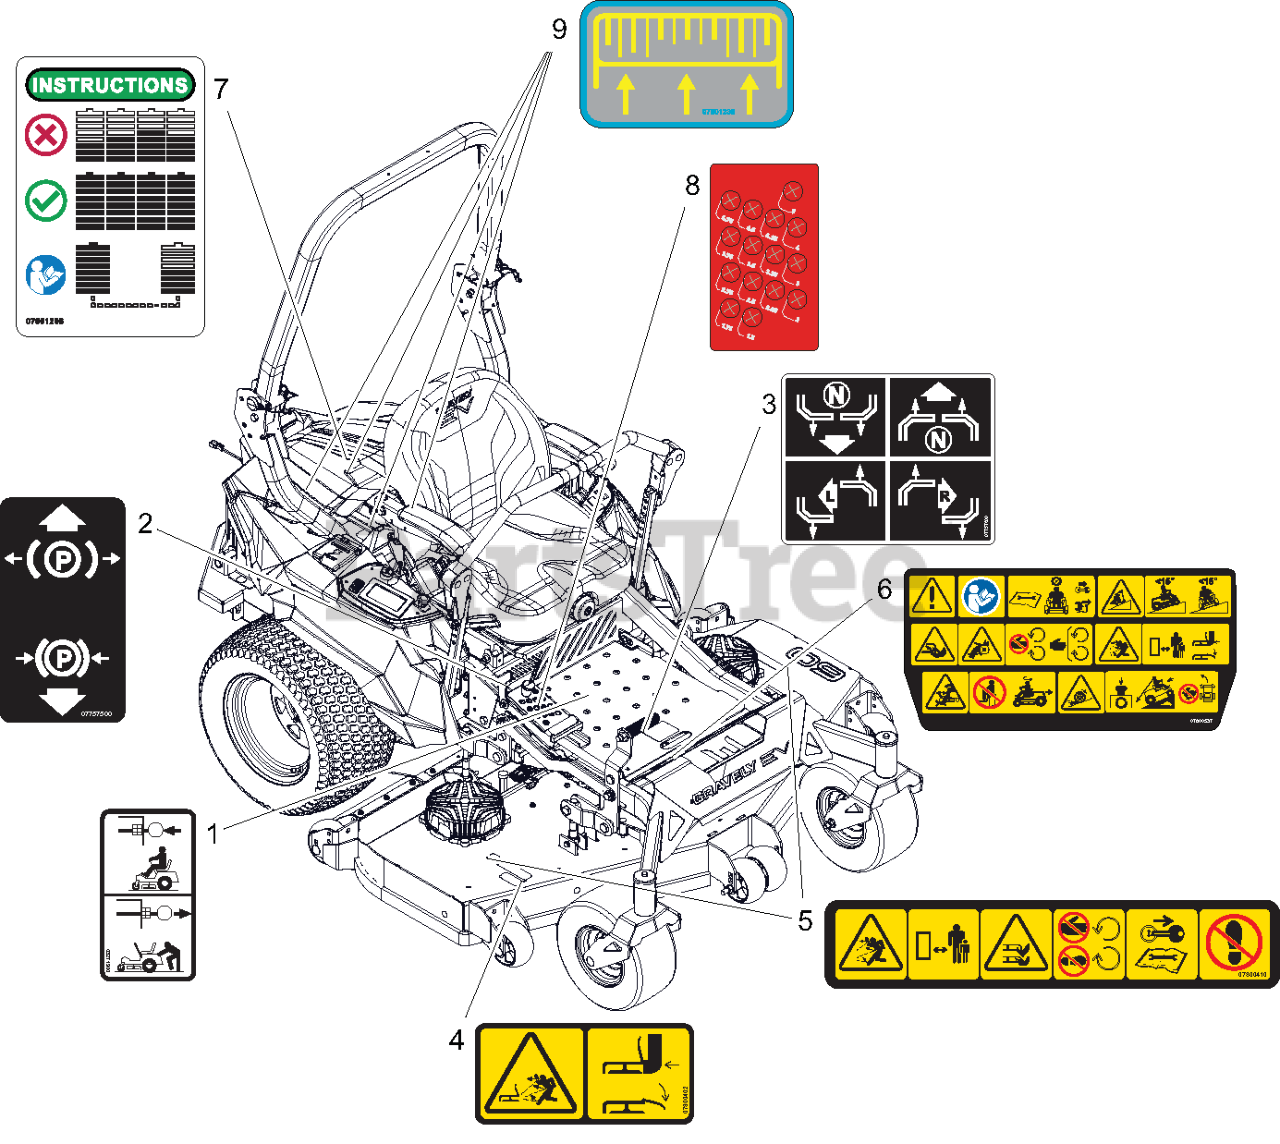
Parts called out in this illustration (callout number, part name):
1	DECAL, TRANSMISSION DISCONNECT
2	DECAL, PARKING BRAKE LEVER
3	DECAL, INSTRUCTIONAL-STEERING
4	DECAL, SAFETY - DECK GUARDING
5	DECAL, DECK SAFETY
6	DECAL, MAIN SAFETY
7	DECAL, BATTERY BALANCE
8	DECAL, HEIGHT OF CUT
9	DECAL, BATTERY INSTALL DIRECTION
